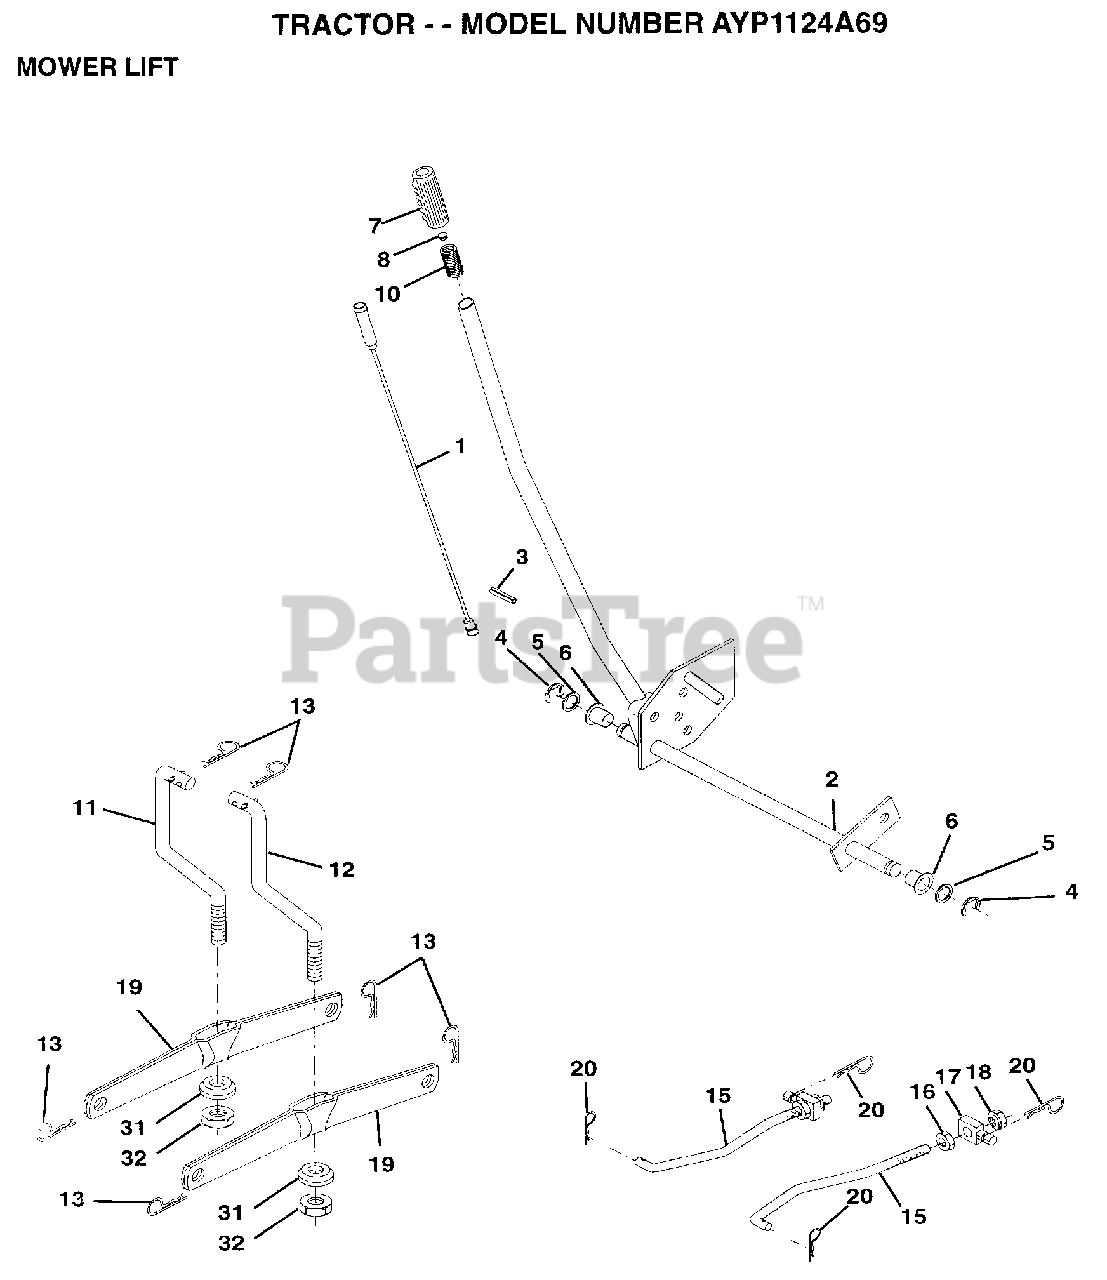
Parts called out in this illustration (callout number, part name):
1	WIRE ASM
2	HANDLE.LIFT.LH.
3	PIN GROOVE
5	WASHER
6	NYLON BEARING
7	GRIP
15	LINK.FRONT
16	NUT
17	TRUNION
18	NUT.LK.W/WSH.1/2.
19	ARM SUSP REAR
20	RETAINER.SPRING
31	BEARING PVT LH
32	NUT.CROWNLOCK.3/8
